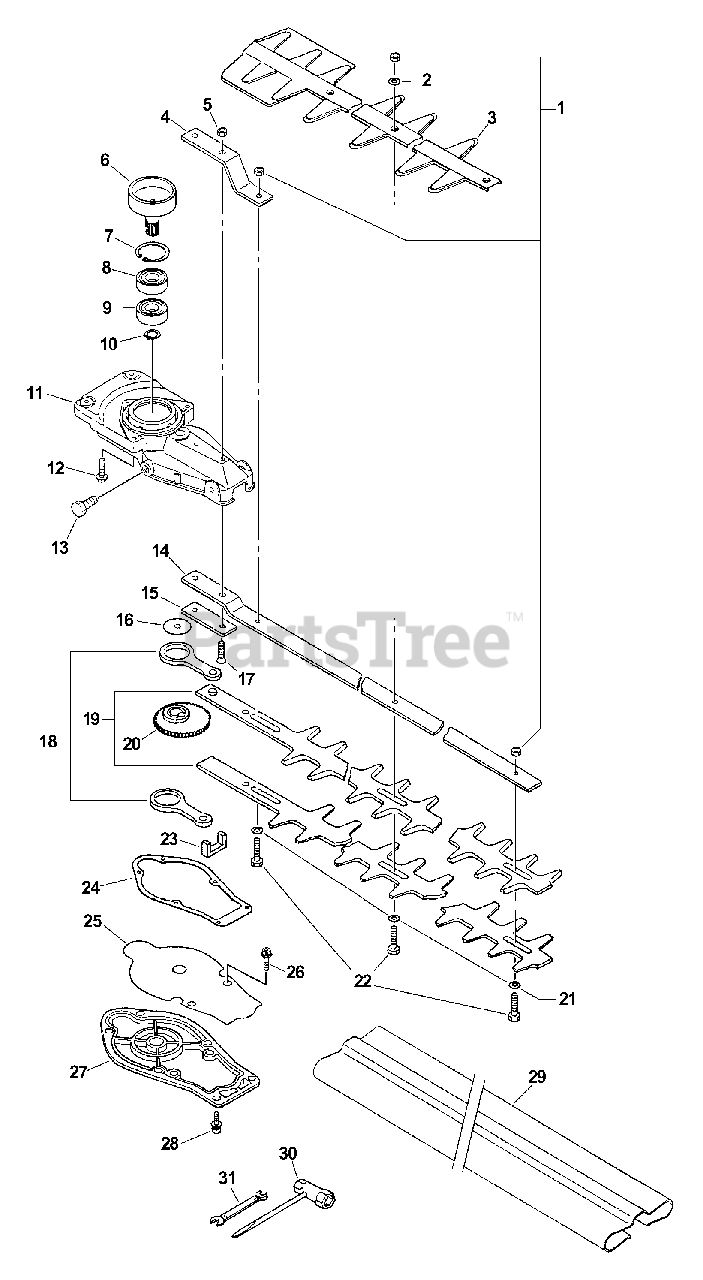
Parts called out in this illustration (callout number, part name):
1	LOCKNUT - 6
2	WASHER - 6
3	SUPPORT, BLADE
4	PLATE, ANGLE
5	LOCKNUT - 6
6	DRUM, CLUTCH
7	RING, RETAINING - 35
8	BEARING, BALL - 6202
9	BEARING, BALL - 6202
10	RING, RETAINING - 14
11	CASE, GEAR - UPPER
12	SCREW - 5X25
13	BOLT - 8X8
14	SUPPORT, BLADE
17	SCREW - 6X25
18	ROD, CONNECTING
19	BLADE, TRIMMER
20	GEAR - DRIVE
21	WASHER - 6
23	SEAL, FELT
24	GASKET, GEAR CASE
25	LID, GEAR CASE
26	SCREW - 5X12
27	LID, GEAR CASE - LOWER
28	SCREW - 4X12
29	COVER, BLADE
30	T-WRENCH - 13X19mm
31	SPANNER - 8X10mm
